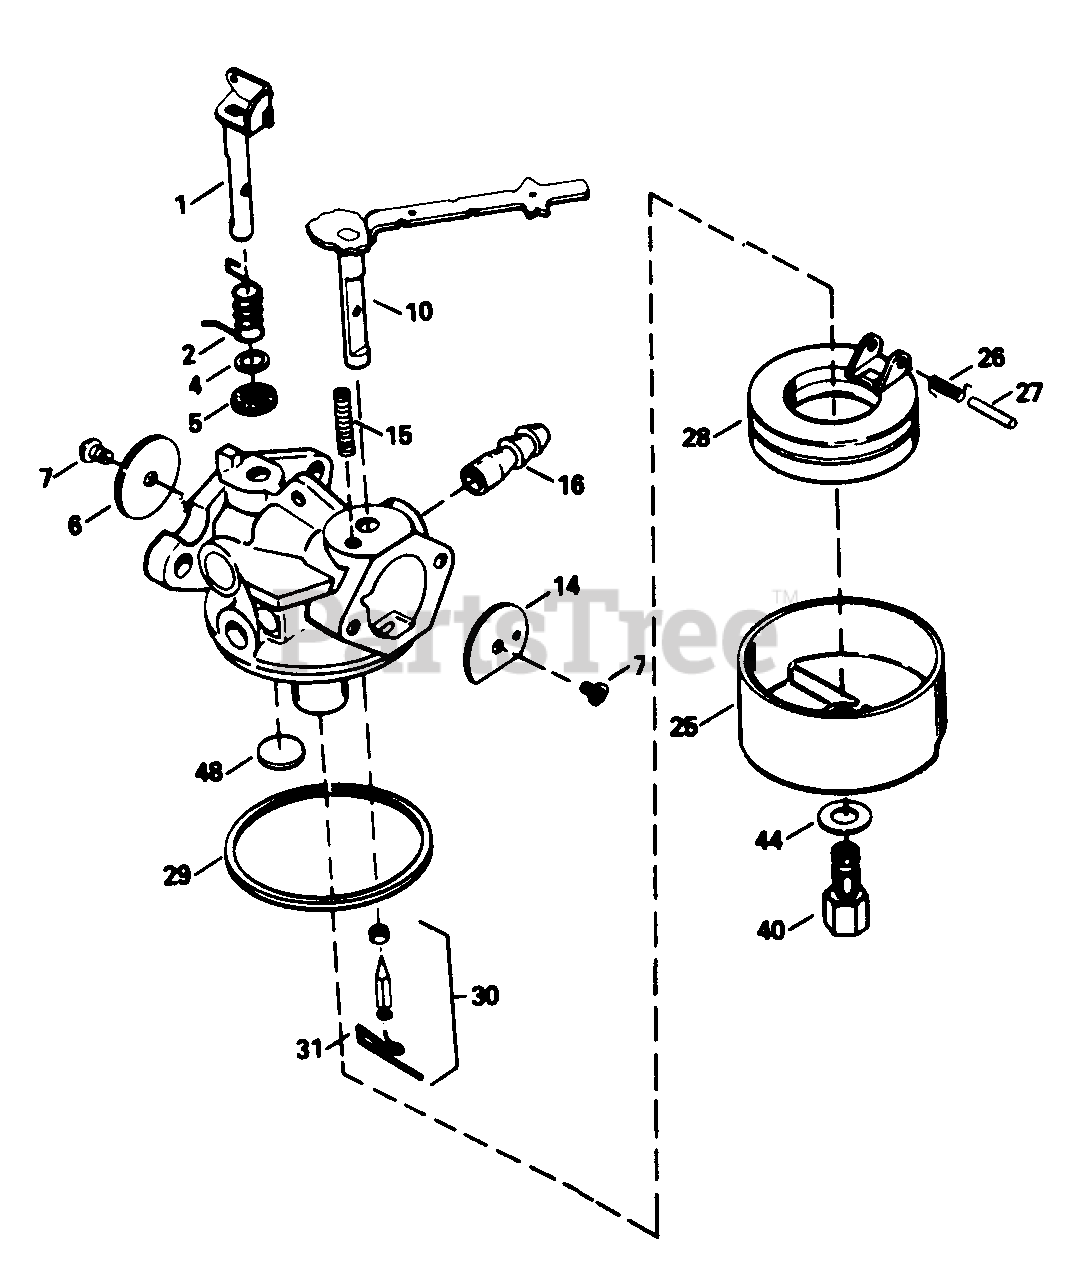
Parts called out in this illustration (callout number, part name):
1	Throttle Shaft & Lever Ass'y.
2	Throttle Return Spring
4	Dust Seal Washer (Throttle)
5	Dust Seal (Throttle)
6	Throttle Shutter
7	Throttle & Choke Shutter Screw
10	Choke Shaft & Lever Ass'y.
14	Choke Shutter
15	Choke Positioning Spring
16	Fuel Fitting
25	Float Bowl
26	Float Dampening Spring
27	Shaft, Float
28	Float
29	O-Ring, Float Bowl to Body
30	Inlet Needle, Seat & Clip
31	Spring Clip
40	High Speed Bowl Nut
44	Bowl Nut Washer
48	Welch Plug, Atmospheric Vent
